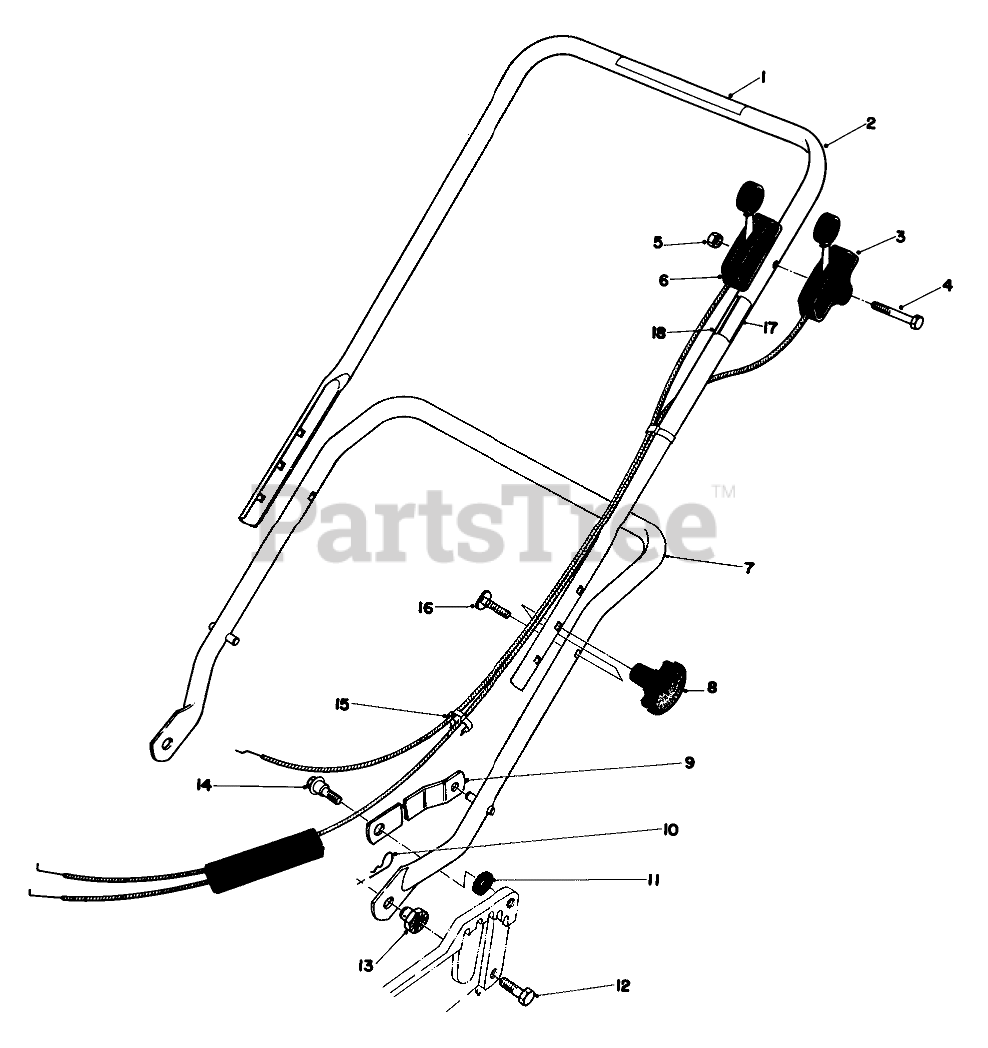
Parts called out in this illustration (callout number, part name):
1	Decal Danger (French & Dutch)
2	Upper Handle
3	Traction Control
4	SCREW-HH
5	NUT-LOCK
6	Throttle Control
7	LOWER HANDLE ASM
9	HANDLE LATCH
10	PIN-COTTER, HAIR
11	SPACER
12	SCREW-HH
13	HANDLE PIVOT NUT
14	SCREW-SHOULDER
15	BOWDEN CLIP
16	SCREW-HANDLE
17	Decal Traction Control
18	Decal Throttle Control
